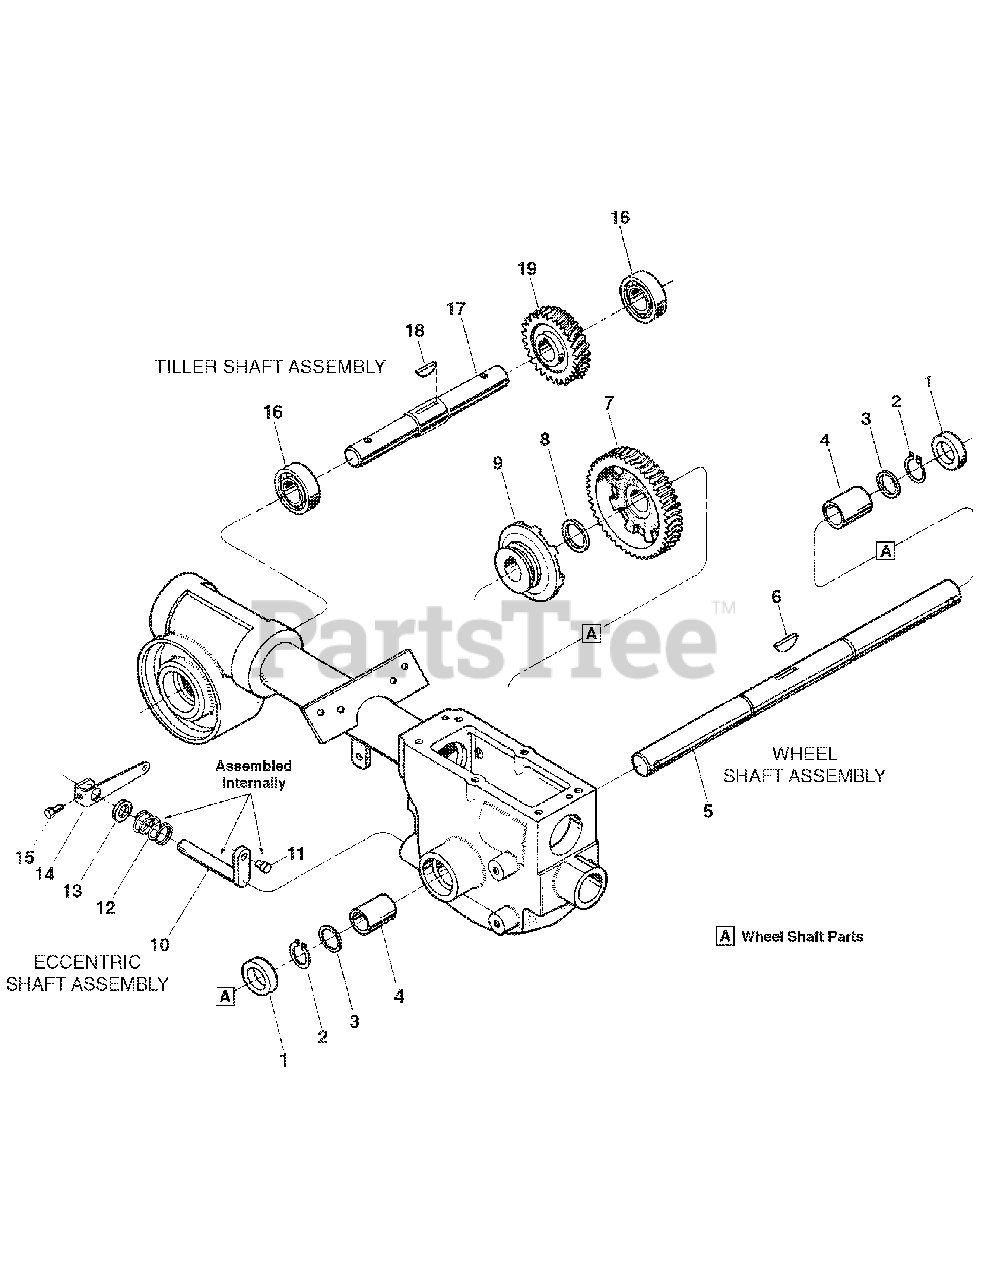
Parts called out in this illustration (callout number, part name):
1	Oil Seal
2	Retaining Ring (heavy-duty, external)
3	Shim, 1-1/64 I.D., .062" thick
3	Shim, as above, but .030" thick
3	Shim, as above, but .015" thick
3	Shim, as above, but .010" thick
4	Bushing
5	Wheel Shaft
6	Hi-Pro Key, 1/4 x 1-5/16
7	Wheel Drive Worm Gear (cast-iron)
8	Shim (between key and gear), 1.016 I.D. x 1.468 O.D. x.062 Thick
9	Wheel Drive Clutch (cast-iron)
10	Eccentric Shaft
11	Pin, Eccentric Shaft
13	Oil Seal
14	Eccentric Shaft Lever
15	Hex Hd. Screw, 1/4-20 x 1/2
16	Ball Bearing
17	Tiller Shaft
18	Woodruff Key, 1/4 x 1-1/4
19	Tiller Drive Worm Gear (bronze)
